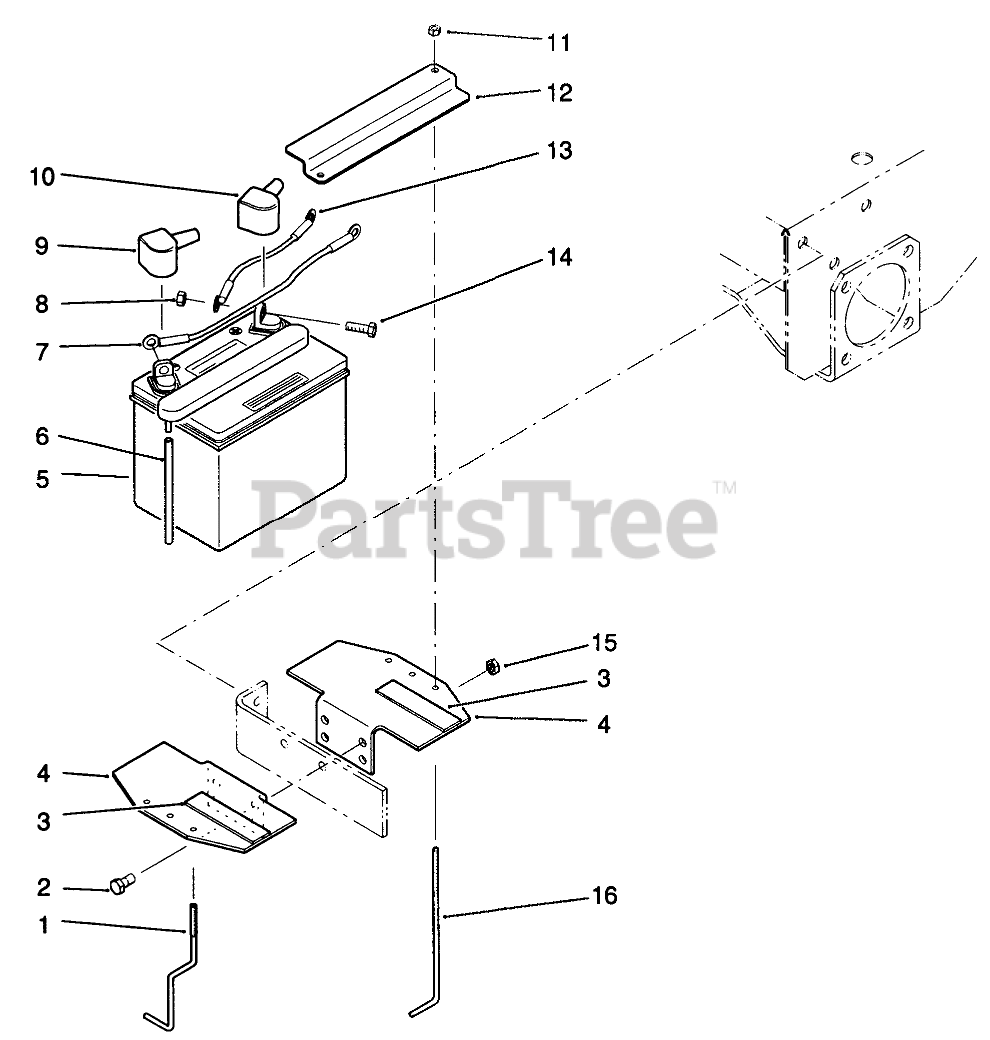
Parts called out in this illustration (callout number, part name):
1	Rod-Battery Support
2	SCREW-HH
3	PAD-TANK, FUEL
4	Holder-Battery
5	Battery
6	TUBE-VENT
7	WIRE ASM
8	NUT-KEPS
9	BOOT-TERMINAL, BLACK
10	BOOT-TERMINAL, RED
11	NUT-LOCK, NI
12	Clamp-Battery
13	WIRE ASM
14	SCREW-HH
15	NUT-LOCK, NI
16	ROD-SUPPORT, BATTERY
